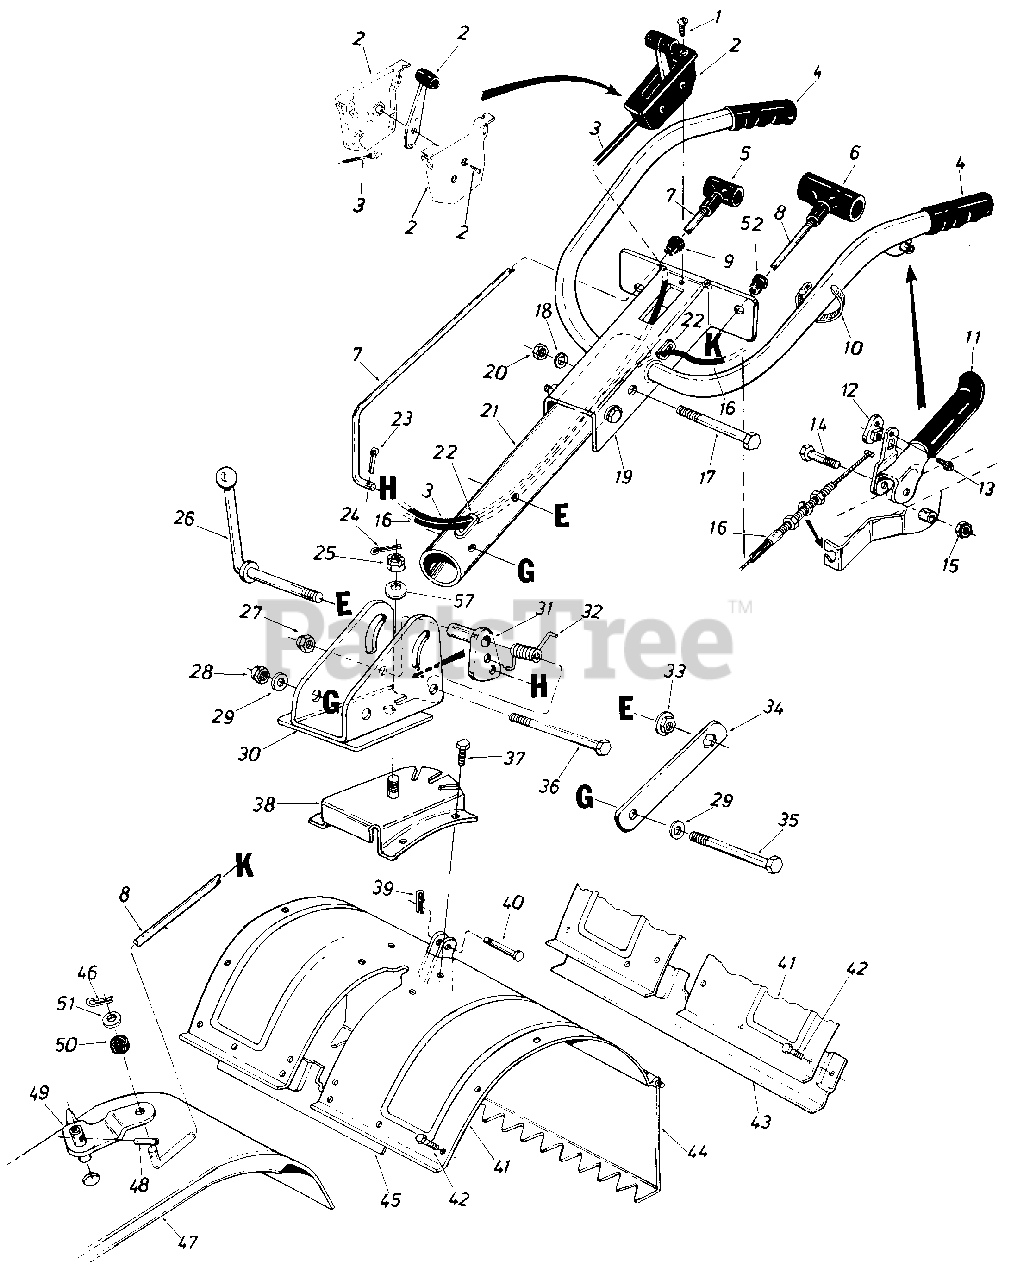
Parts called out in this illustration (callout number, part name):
1	Truss Mach. AB-Tap. Scr. #10 x .50" Lg.
2	Throttle Control Box Ass'y.
3	Throttle Control Wire
4	Handle Grip
5	Small "T" Knob
6	Large "T" Knob
7	Clutch Rod
8	Control Rod .33 Dia. x 37"
9	Snap On Bushing 3/8" Dia.
10	Cable Tie-Self Clinching
11	Clutch Grip Ass'y.-L.H.
12	Barrel Cable Hold Down
13	Hex B-Tap Scr. #10 x .44" Lg.
14	Hex Bolt 3/8-16 x 2.0" Lg.
15	Hex Cent. L-Nut 3/8-16 Thd.
16	Clutch Control Cable 53" Lg.
17	Hex Bolt 3/8-16 x 3.00" Lg.
18	L-Wash. 3/8" I.D.-H.D.
23	Cotter Pin 3132" Dia. x .75" Lg.
24	Cotter Pin 3132" Dia. x 1.25" Lg.*
25	Hex Slotted Nut 5/8-18 Thd.
26	Handle Adj. Crank
27	Hex Cent. L-Nut 3/8-16 Thd.
28	Hex Nut 3/8-16 Thd.
29	Bell-Wash. .400" I.D. x .87" O.D.
30	Handle Pivot Bracket
31	Positioner Crank Ass'y.
32	Spring Handle Adj.
33	Hex Flange Nut 3/8-24 Thd.
34	Bracket Hex Nut Retainer
35	Hex Bolt 3/8-16 x 3.25" Lg.
36	Hex Bolt 3/8-16 x 3.00" Lg.- Gr. 8
37	Hex Bolt 3/8-16 x .75" Lg.
38	Handle Positioner Brkt. Ass'y.
39	Intern. Cotter Pin
40	Clevis Pin .375" Dia.
42	Hex Bolt 5/16-18 x .75" Lg.
43	Bracket Reinforcement- 18"
45	Bracket Reinforcement-14"
46	Intern. Cotter Pin 5/16" Dia.
47	Shift Cover
48	Spring Roll Pin 3/16" Dia. x 1.00" Lg.
49	Shifting Crank Ass'y. D x 2.05
50	Rubber Washer .33" I.D. x .87" O.D.
51	Fl-Wash. .400" I.D. x 1.250" O.D.
52	Snap On Bushing 1/2" Dia.
57	Bell-Wash. .630" I.D. x 1.25" O.D.
